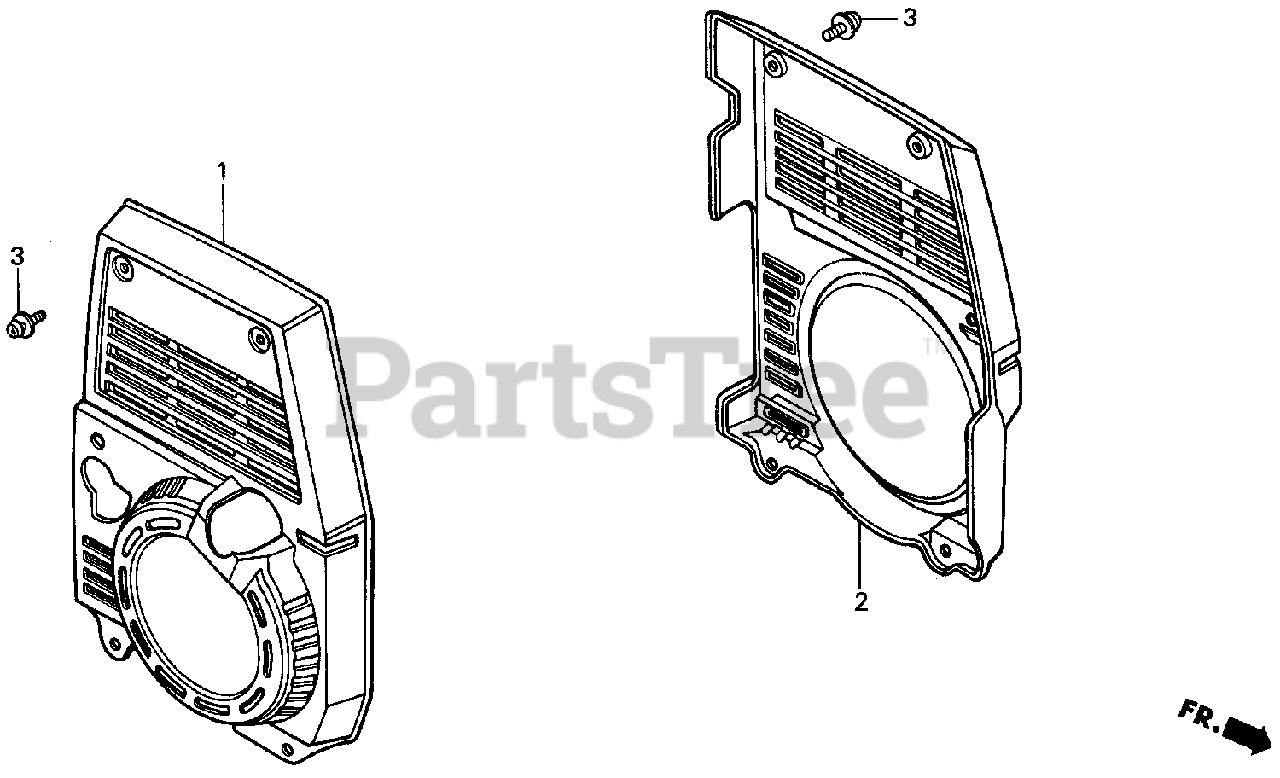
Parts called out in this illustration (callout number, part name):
1	COVER, L. SIDE *NH35M* (CLOUD SILVER METALLIC)
1	COVER, L. SIDE *NH1* (BLACK)
2	COVER, R. SIDE *NH35M* (CLOUD SILVER METALLIC)
2	COVER, R. SIDE *NH1* (BLACK)
3	SCREW-WASHER (5X10)
